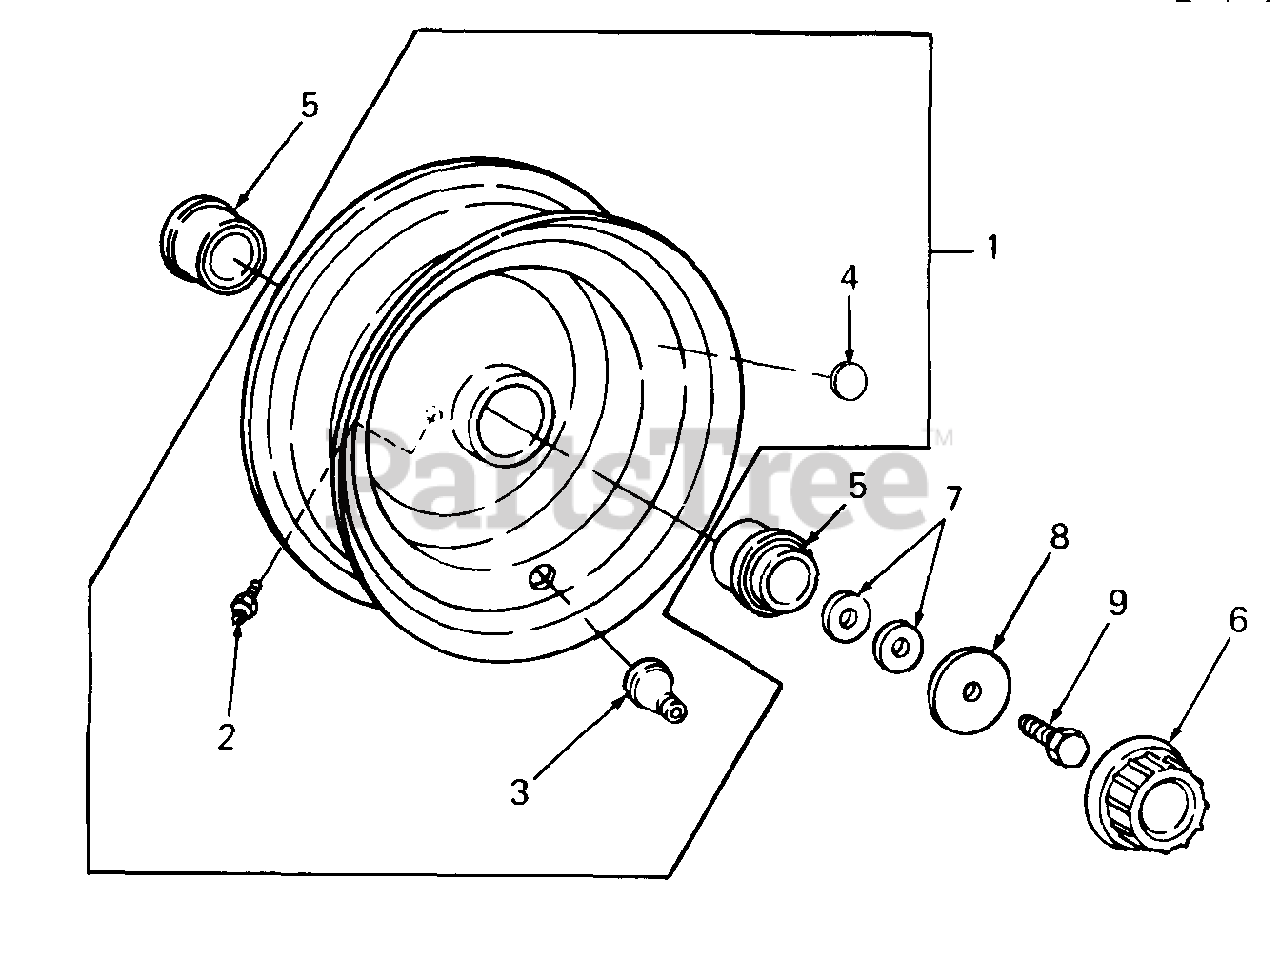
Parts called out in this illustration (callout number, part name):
1	Wheel Assy, Front
2	Fitting, Lube
3	Valve, Tubeless Air
4	Label, Inflation
5	Bearing, Wheel Ball
6	Cap, Hub
7	Washer, Flat, .531 X 1.25 X. 100 Thk
8	Washer, Flat, .535 X 1.92 X .060 Thk
9	Bolt, Patch, 1/2-13 X 1.0 Lg GR5
